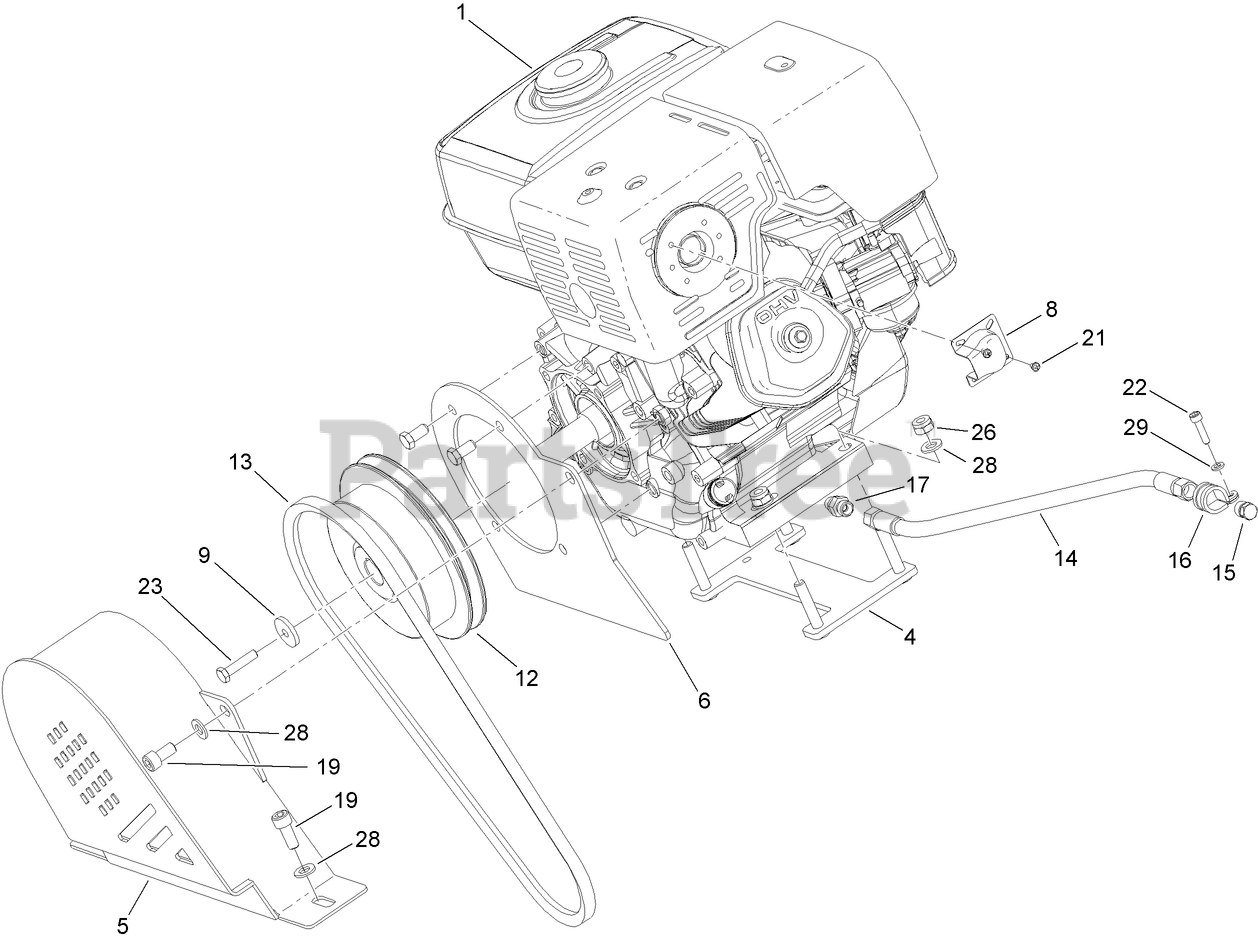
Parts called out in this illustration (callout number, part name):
1	ENGINE-HONDA
4	CONTROL-ENGINE
5	COVER-PULLEY
6	HOLDER-COVER
8	DEFLECTOR-EXHAUST
9	WASHER
12	COUPLING
13	V-BELT
15	PLUG-OIL
16	CLIP-HOSE
17	SOCKET-STRAIGHT
28	WASHER
29	WASHER
